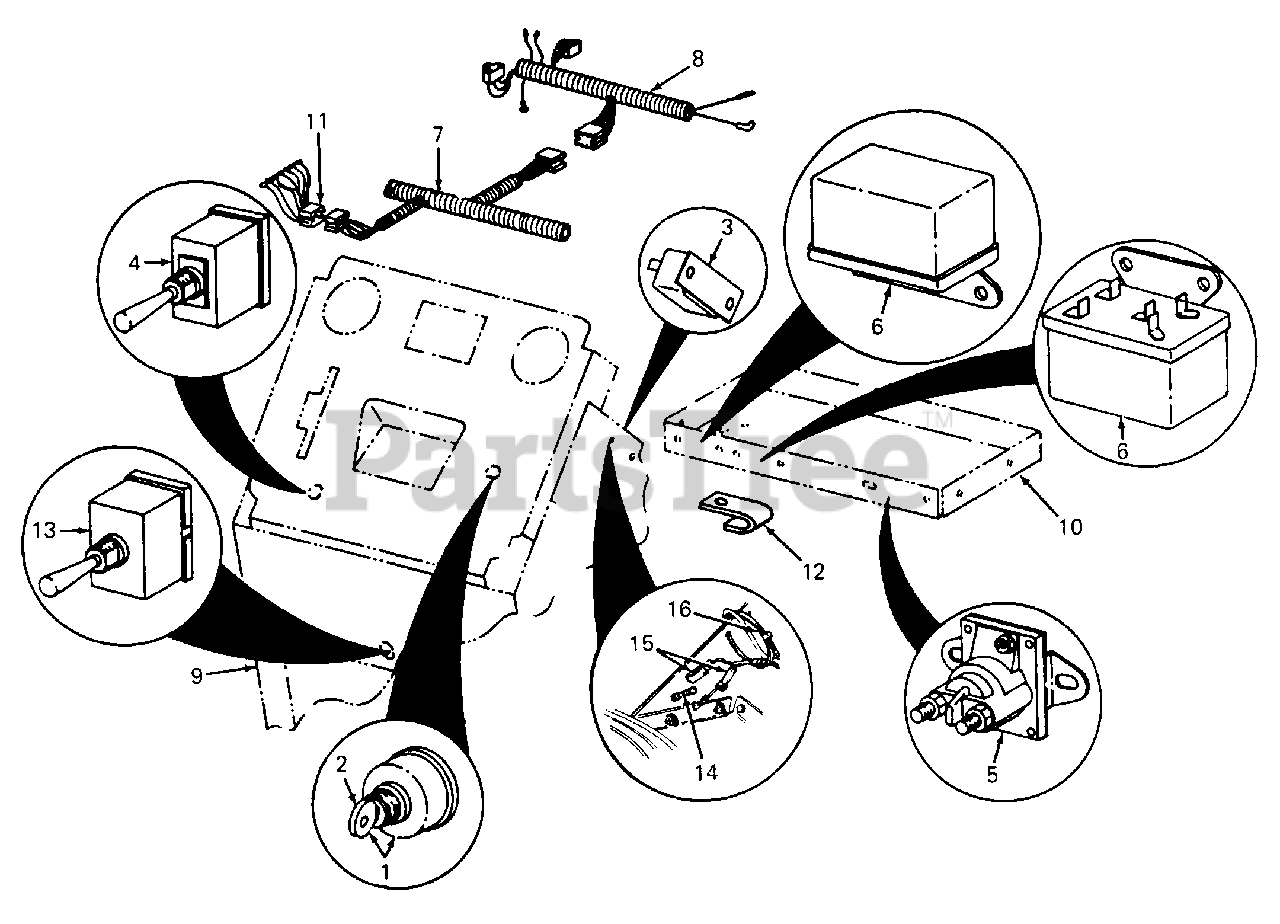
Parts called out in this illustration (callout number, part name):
1	Switch, Key
2	Key, Ignition (Set of 2)
3	Breaker, Circuit
4	Switch, PTO
5	Switch, Solenoid
6	Relay
7	Harness, Battery Tray
8	Harness, Main Wiring
10	Tray, Battery
11	Harness, Indicator
12	Clip, Cable
13	Switch w/Nut, Light
14	Fuse
15	Fuse Holder
16	Cable Tie
